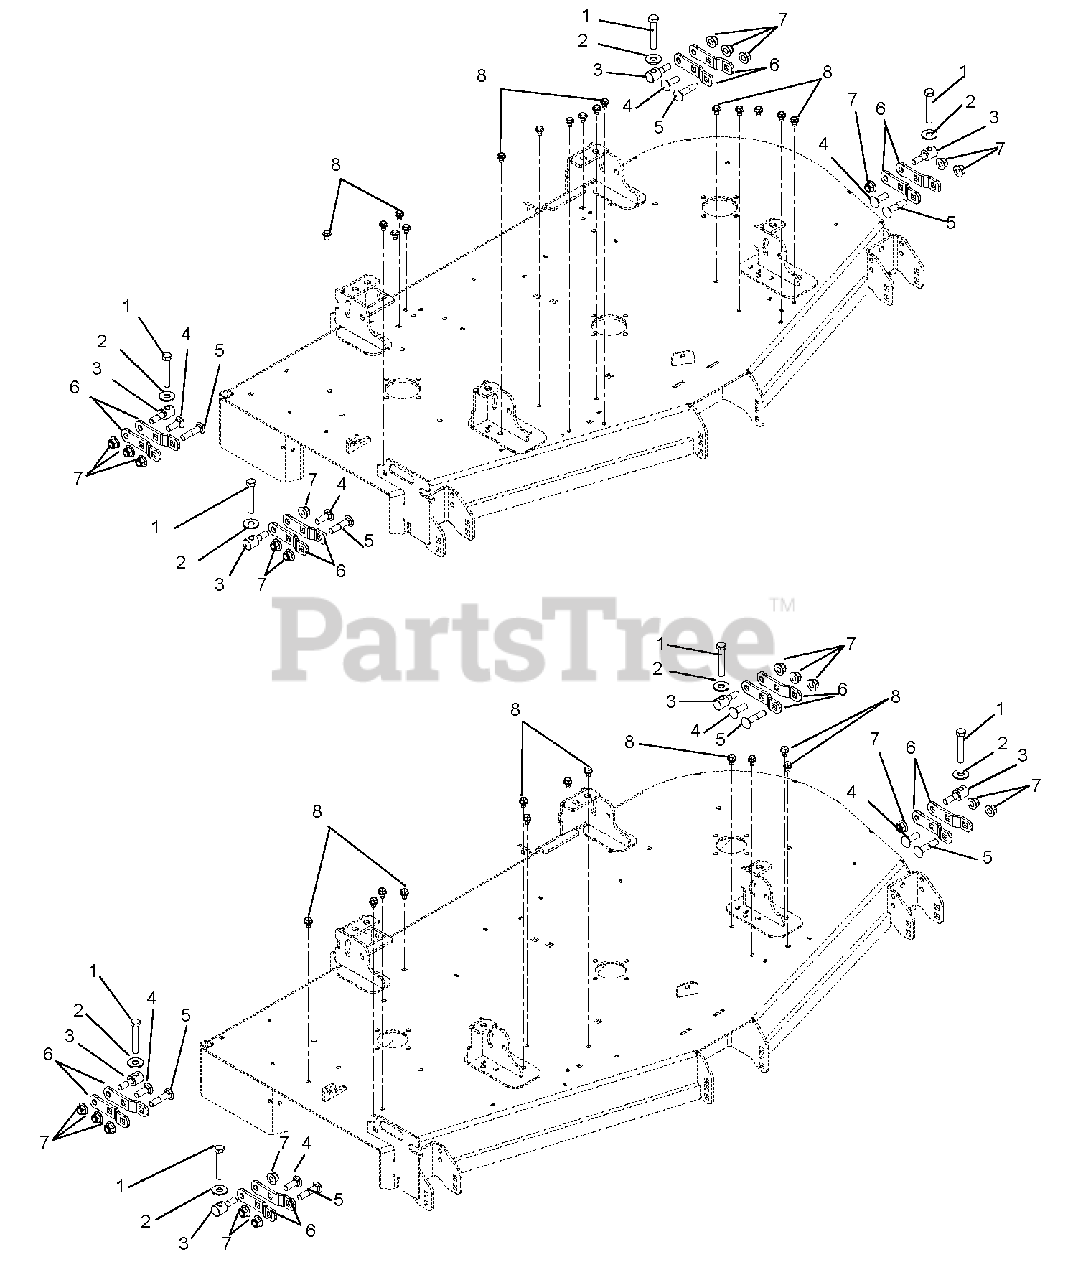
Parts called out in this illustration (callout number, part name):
1	Bolt, Hex .50-13 x 3.00 Grade 5 Full Thread
2	Washer, Flat-Steel .563 x 1.38 x .109
3	Trunnion, .50-13
4	Bolt, Round Head Square Neck .50-13 x 1.50 Grade 5
5	Bolt, Round Head Square Neck .50-13 x 2.25 Grade 5
6	Deck Leveling Bracket- Black
7	Nut, Locking-Nylon-Flange .50-13
8	Screw, Tapping .38-16 x .50 Hex Washer Head
